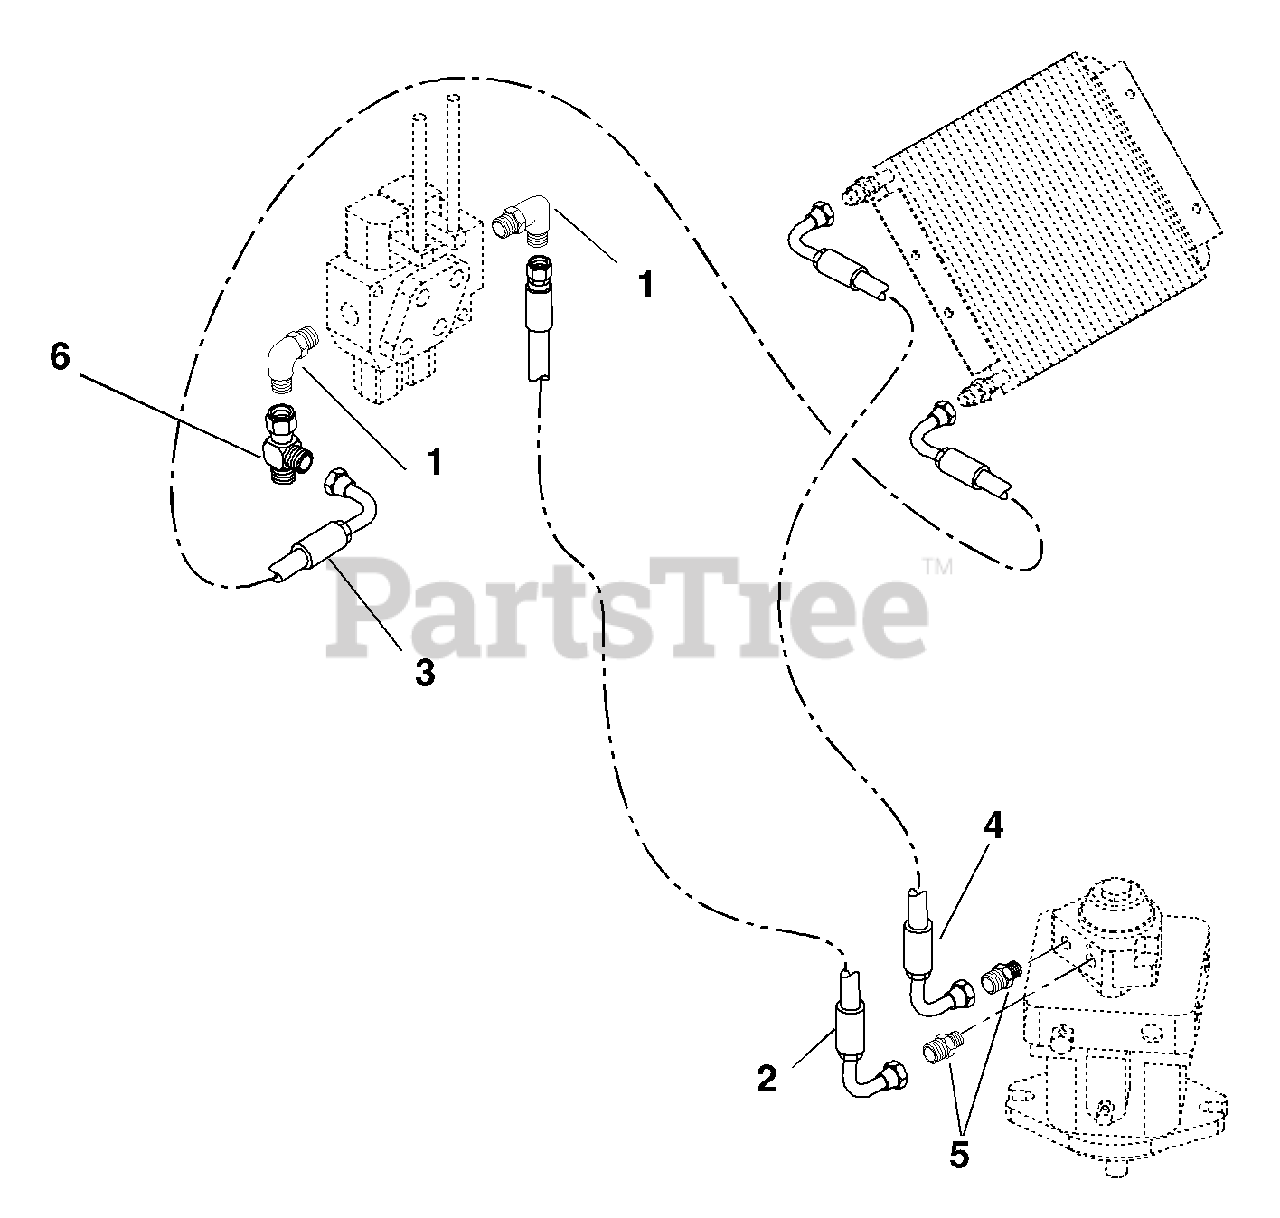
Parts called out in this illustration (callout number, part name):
1	Fitting, Hydraulic Elbow
2	Hose, Hydraulic
3	Hose, Hydraulic
4	Hose, Hydraulic
5	Fitting, Hydraulic
6	Fitting, Hydraulic
